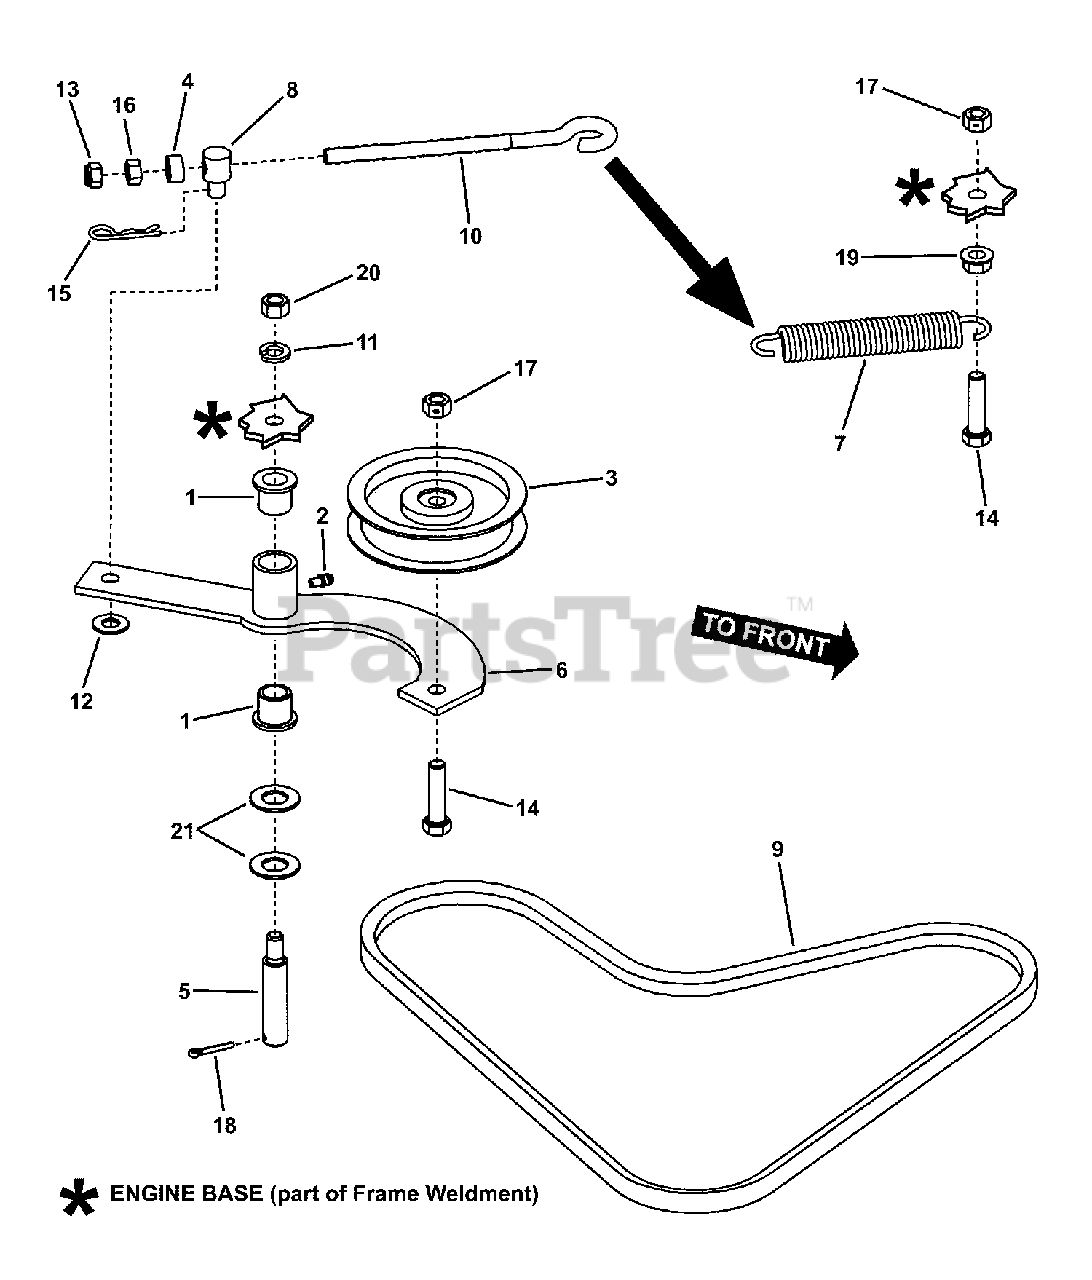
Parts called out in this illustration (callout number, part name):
1	BEARING, 9/16" I.D. Flange
2	LUBE FITTING, 3/16"
3	FLAT IDLER, 4.12 O.D.
4	SPACER, .340 I.D. x .63 O.D. x .310 Thick
5	IDLER STUD (3/8-24)
6	WELDMENT, Idler Arm
7	SPRING, Extension
8	SWIVEL, Adjustable
9	* BELT, Traction Drive (HA Section, 47.5 Effective Length)
9	* BELT, Traction Drive (4L Section, 48.3 Effective Length)
10	EYEBOLT, 5/16-18
11	WASHER, 3/8" Split Lock
12	WASHER, 3/8" SAE Flat
13	NUT, 5/16-18 HEX NYLON LOCK
14	SCREW, 3/8-16 x 1-1/2" Hex Head Cap, GR 5
15	HAIR PIN, 3/32 x 1-1/2"
16	NUT, 5/16-18 Hex, GR 5 or B
17	NUT, 3/8-16 Hex Center Lock
18	COTTER PIN, 1/8 x 3/4"
19	NUT, 3/8-16 HEX SERRATED FLANGE
20	NUT, 3/8-24 HEX
21	WASHER, 9/16" Flat (Type Narrow)
